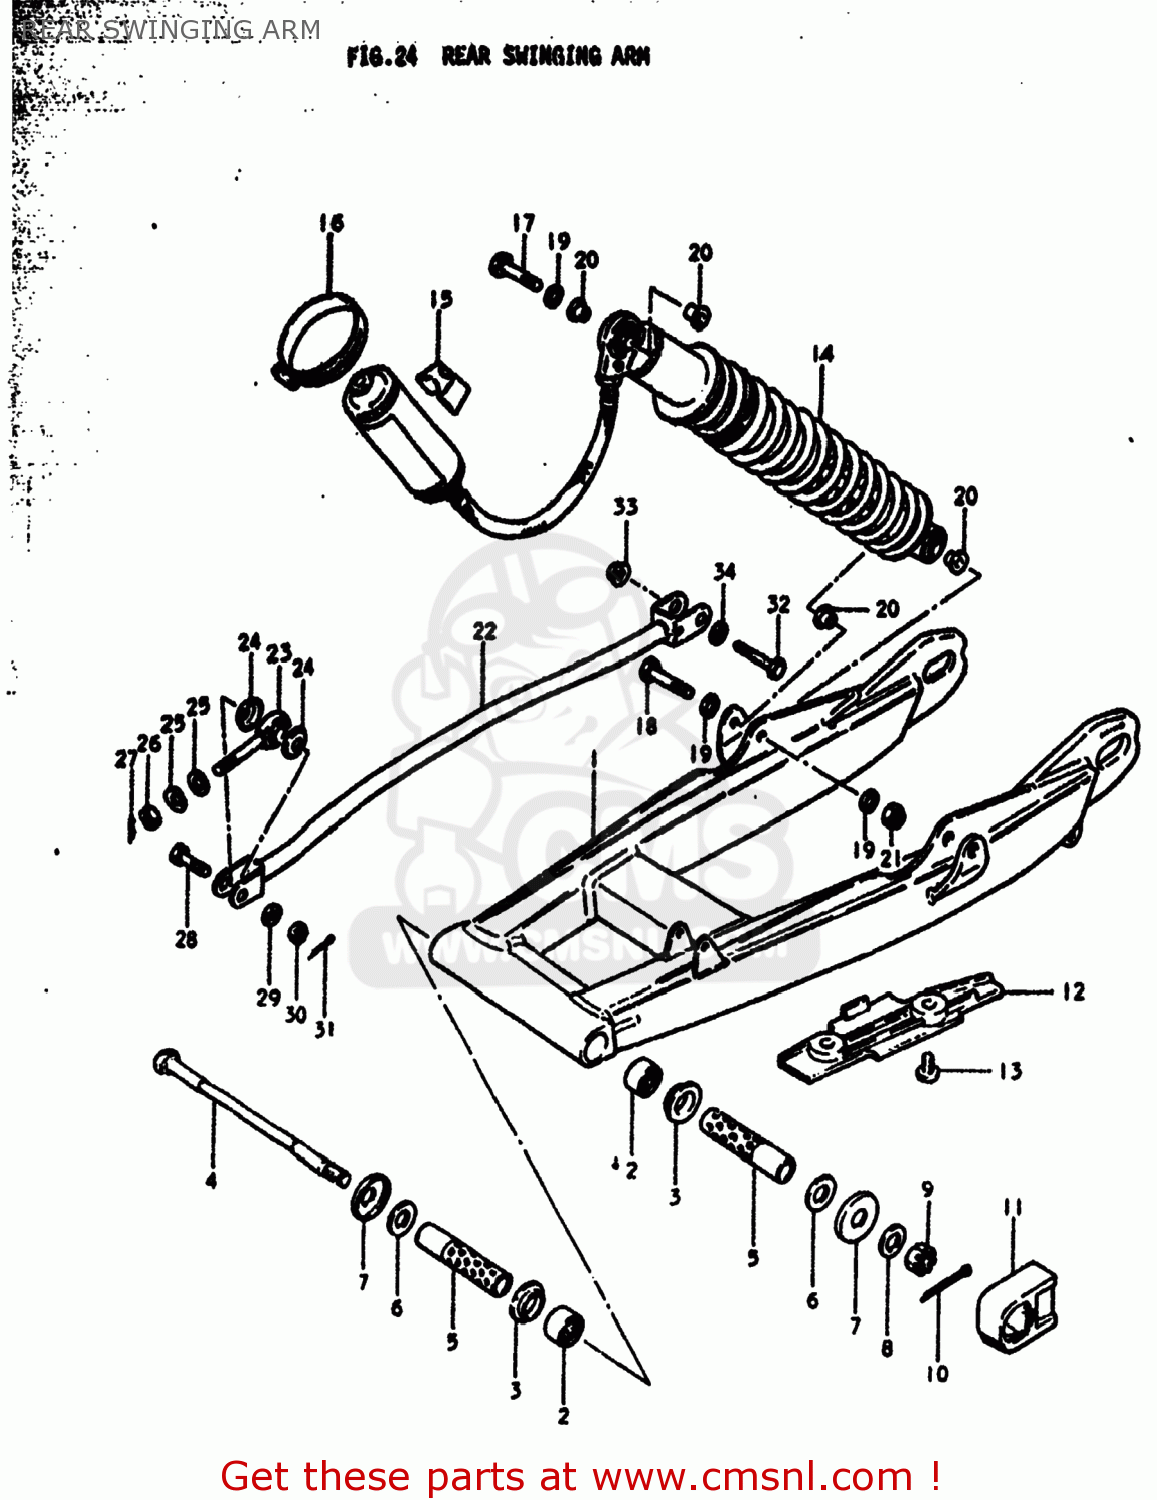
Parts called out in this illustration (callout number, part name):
1	SWING ARM ASSEMBLY,REAR
2	BEARING
3	BUSHING,REAR SWING ARM PIVOT
4	SHAFT,REAR SWING ARM
5	SPACER,REAR SWING ARM
6	WASHER
7	COVER,RR SWGARM DUST SEAL
8	WASHER
9	NUT 14MM
10	COTTER PIN
11	BUFFER,CHAIN TOUCH DEFLECTOR
12	BUFFER,CHAIN TOUCH DEFLECTOR
13	SCREW
14	ABSORBER ASSEMBLY,REAR SHOCK
15	CUSHION,RR SHOCK ABSORBER
16	CLAMP
17	BOLT
18	BOLT(8X46)
19	WASHER
20	SPACER,RR SHK ABS INNER
21	NUT
22	LINK,REAR TORQUE
23	BEARING
24	DUST SEAL,TORQUE LINK FR BRG
25	WASHER
26	NUT
27	CLIP
28	BOLT 8X28
29	WASHER
30	NUT 8MM
31	PIN 20X20
32	BOLT 10X40
33	NUT
34	WASHER
